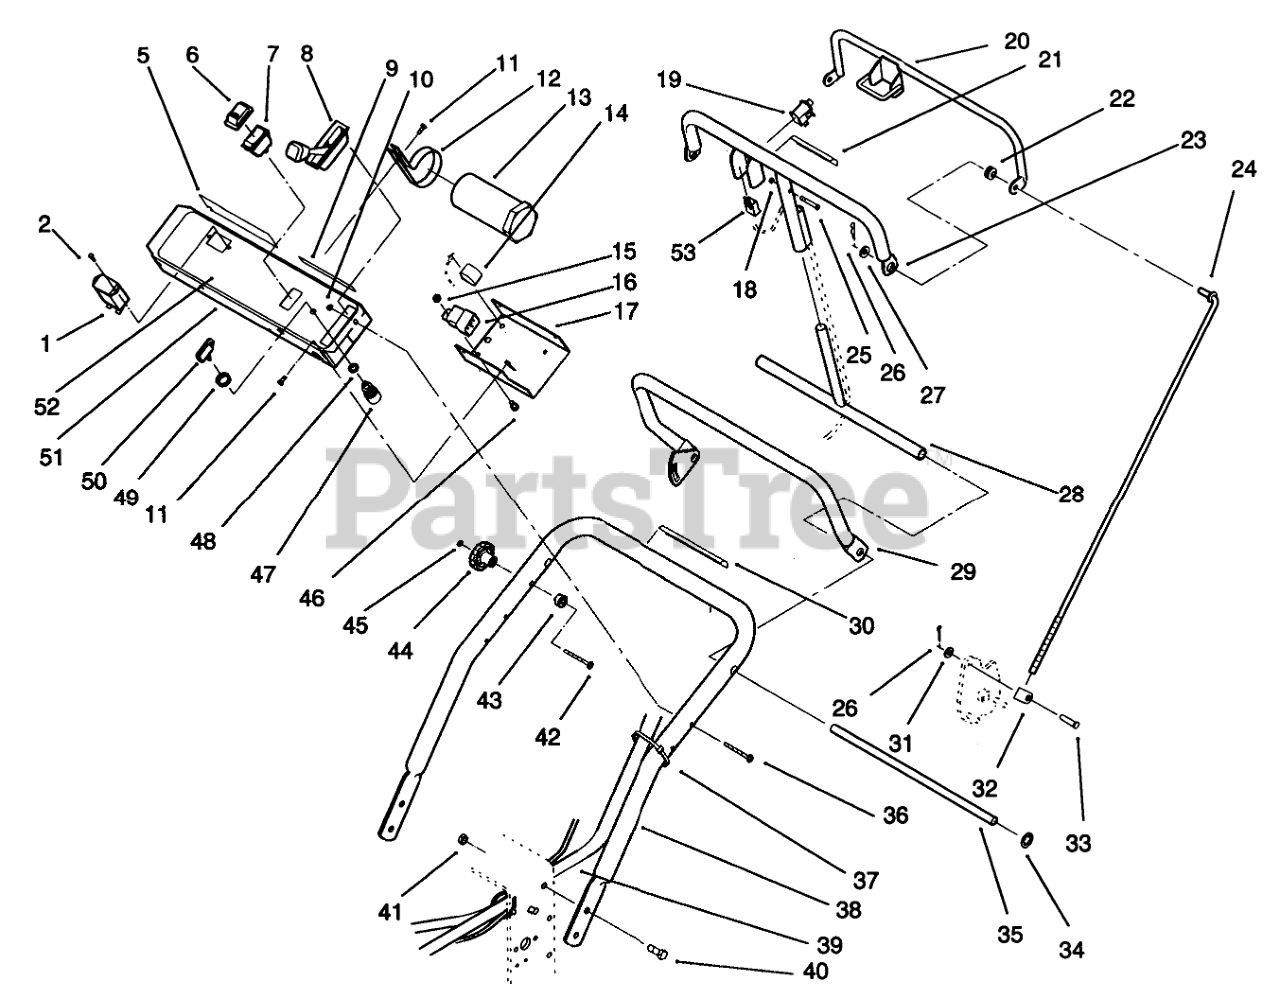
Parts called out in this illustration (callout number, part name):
1	HOURMETER
2	SCREW-HWH
5	DECAL-INSTRUCTION, SAFETY
6	BOOT-SWITCH
7	SWITCH
8	CONTROL-THROTTLE
9	DECAL-INSTRUCTION
10	NUT-LOCK, NI
11	SCREW-HWHTF
12	CLAMP-R
13	TUBE-MANUAL
14	Module
15	NUT-LOCK, NI
16	RELAY
17	Panel-Bottom
18	NUT-LOCK, NI
19	SWITCH-BAIL
20	Bail
21	DECAL - CONTROL BAR
22	GROMMET-RUBBER
23	Bar
24	ROD-CONTROL
25	SCREW-SHH
26	PIN-COTTER
27	WASHER-FLAT
28	Pivot Control Assembly
29	REFERENCE HANDLE WA B
30	DECAL-WARNING
31	WASHER-PLAIN
32	FITTING-ROD
33	PIN-CLEVIS
34	NUT-PUSH-ON, CIRCULAR
35	PIVOT ROD
36	SCREW-SHH
37	TIE-CABLE
38	UPPER HANDLE R
39	WIRE HARNESS
40	SCREW-HHF
41	NUT-HF
42	Bolt Carriage
43	SPACER
45	BOLT RETAINER
46	SCREW-HH
47	SWITCH-STARTER
48	SCREW-HHF
49	NUT-HH
50	KEY-IGNITION
51	DECAL - CONTROL PANEL
52	Panel-Control
53	CONNECTOR-BODY
